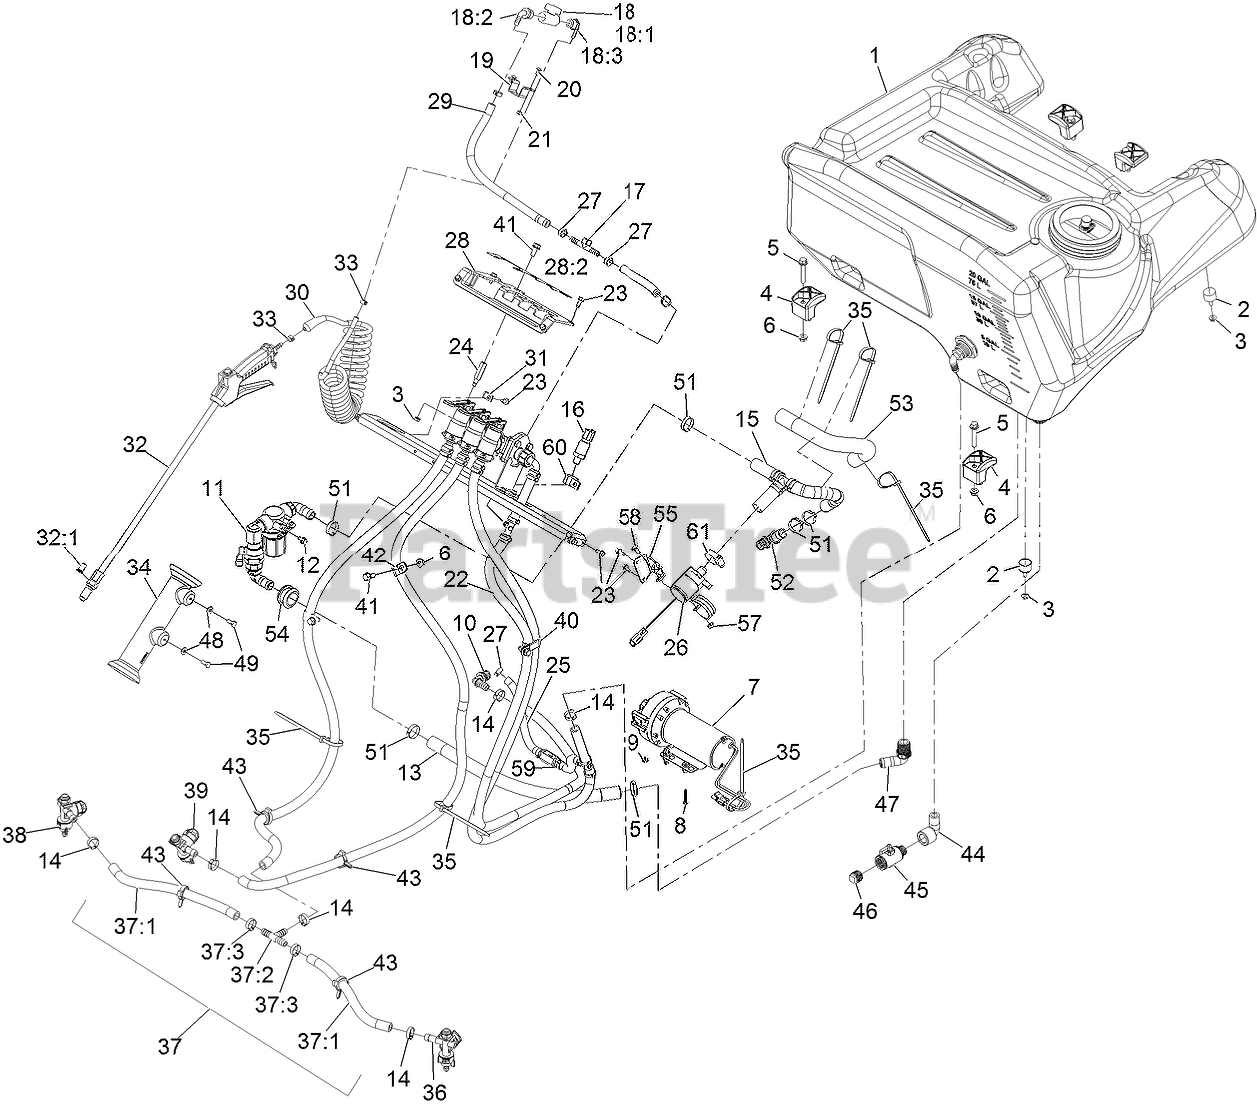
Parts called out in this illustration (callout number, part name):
1	Tank-Sprayer
5	SCREW-HHF
7	Pump-Diaphragm, 3.8 GPM
8	SCREW-SHWH
10	FITTING-ELBOW, BARBED
11	STRAINER ASM
12	SCREW-HHF
13	HOSE-WATER
15	ASM-, 3/4 Pvc Reinforced Water Hose
16	Transducer-Pressure
17	FITTING-TEE
18	Wand Control ASM
18:1	VALVE-BALL
18:2	FITTING-ELBOW-90
18:3	FITTING-ELBOW-90
19	BRACKET-VALVE
20	BOLT-CARR
21	NUT-LOCK, NI
22	Manifold-Valve, Control ASM
23	SCREW-HWH
24	Spacer, Manifold Mount
25	Hose-Water
26	Pump-Centrifugal
28	COVER-CONTROLS
28:2	Decal-Lever Control
29	HOSE-WATER, 3/8 PVC RED
30	HOSE-COILED
31	CLAMP-R
32	SPRAY WAND ASM
32:1	STRAINER-NOZZLE, 50M 5PSI
34	HOLDER-WAND
35	TIE-PLASTIC
36	LEFT NOZZLE SUB ASM
37	HOSE ASM
37:1	HOSE-WATER
37:2	FITTING-TEE
38	RIGHT NOZZLE SUB ASM
39	CENTER NOZZLE SUB ASM
41	SCREW-HHF
42	CLIP-LOOM
43	CLAMP-HOSE
44	ELBOW-90 DEG
45	MICROVALVE
47	ELBOW-HOSEBARB
48	WASHER-FLAT
49	SCREW-HH
52	FITTING-ELBOW
53	SLEEVE-CORRUGATED, SPLIT
54	GROMMET
55	Brkt-Recir Pump
58	SCREW-CARR
59	Valve-3/8 Check
60	R-CLAMP
61	CLAMP-HOSE
